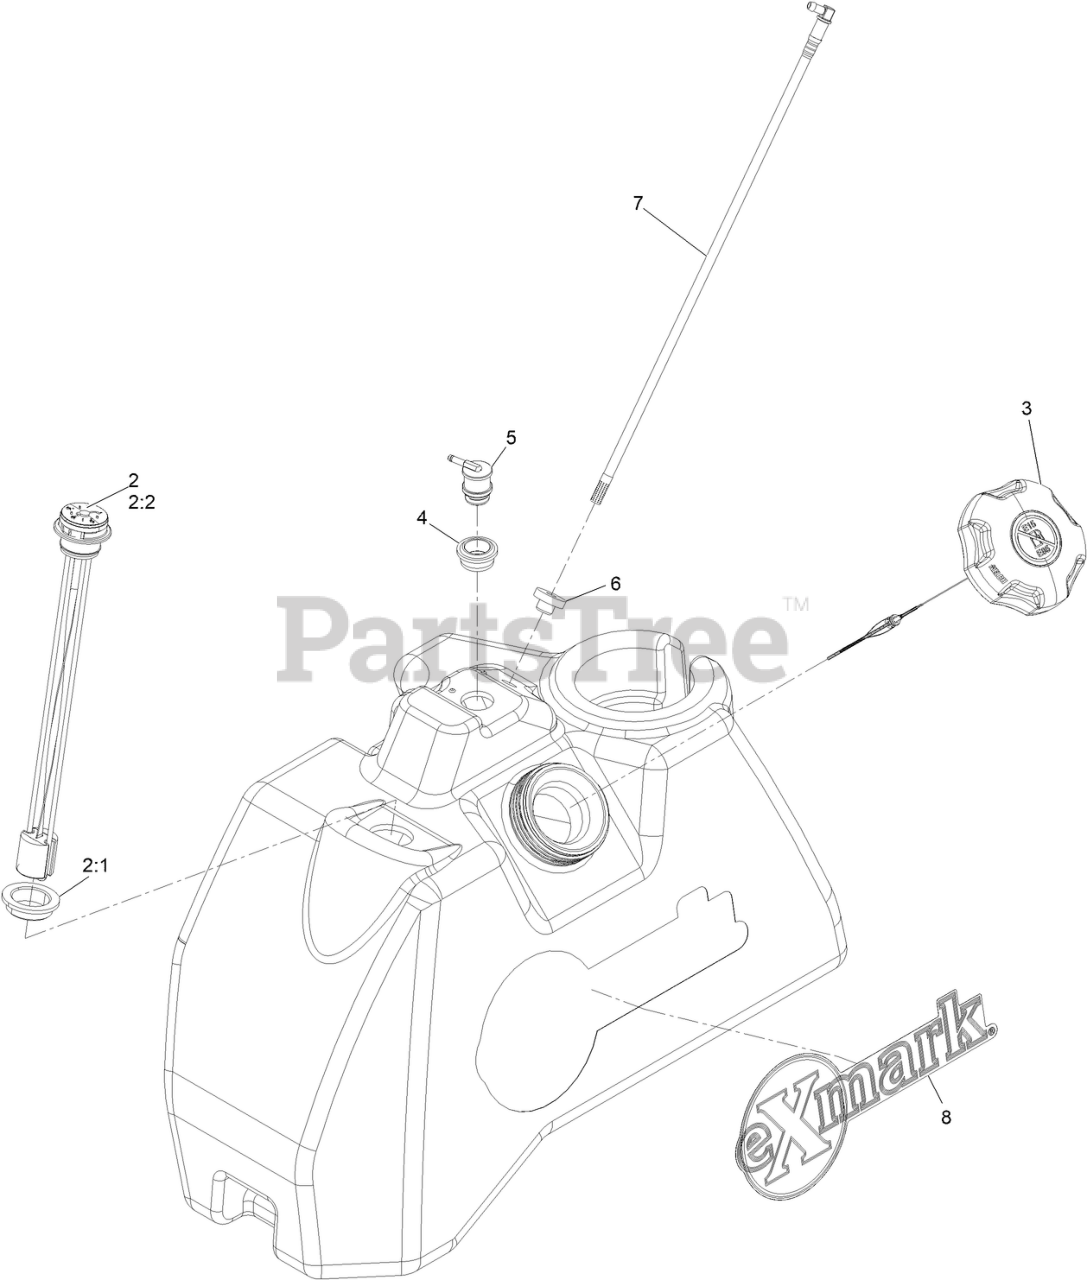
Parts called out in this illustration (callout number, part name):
2	Gauge ASM-Fuel
2:2	Dial-Gauge
3	CAP-FUEL, RATCHETING
4	GROMMET
5	VALVE-VENT, FUEL
6	BUSHING
7	STAND PIPE
8	DECAL-EXMARK LOGO FUEL
